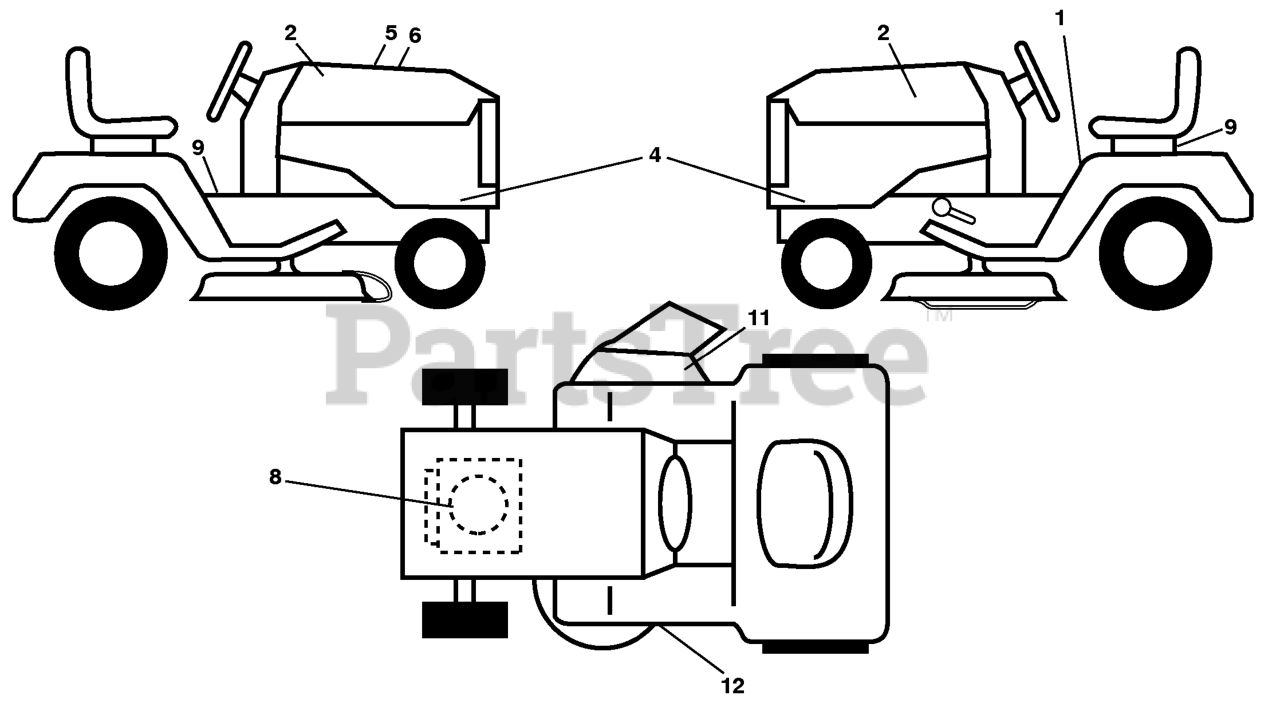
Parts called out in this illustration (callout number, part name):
1	DECAL.FENDER.WARNING.ENG
2	RP.DECAL.BADGE.170MM.TEXTLOGO
4	DECAL PANEL SIDE
5	DECAL.WARNING.CUST.RESP.E85.
6	DECAL.RPL.BSM40.INTK.TLW.42K46
8	DECAL.ENG.BS.20HPXRD.SL.278416
9	DECAL BTRY SYMBOLS
11	DECAL.WARN.KEEP.HAND.AWAY
12	DECAL V BELT SCHEMATIC
